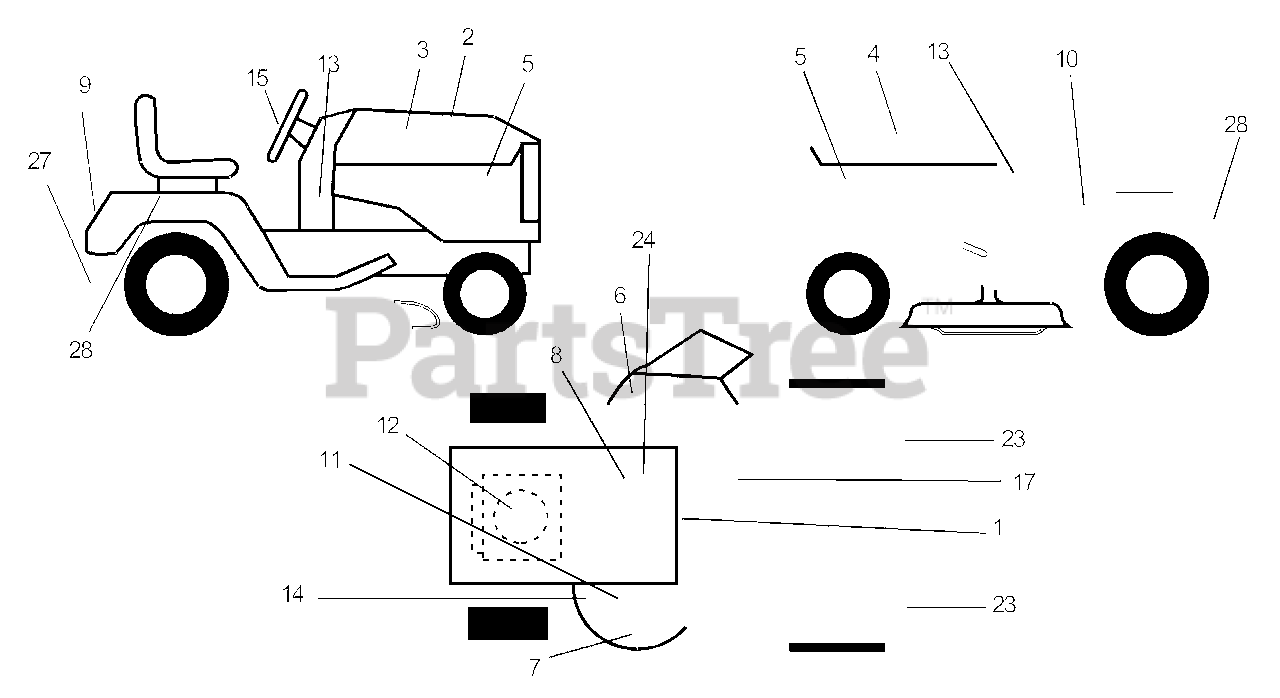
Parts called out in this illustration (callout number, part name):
1	Decal, Operating Instruction
2	Decal, Replt
3	Decal, Hood, RH
4	Decal, Hood, LH
5	Decal, Side Pnl
6	Decal, Warning
7	Decal, Deck Mul
8	Decal, Batt Power Pro
9	Decal, Fender
10	Decal, Danger
11	Decal, Clutch/Brake
12	Decal, Engine
13	Decal, Dash Panel
14	Decal, V-Belt Schematic
15	Decal, Ins. Whl. Strg.
17	Decal, Saddle Brake Parking
23	Reflector, Taillight
24	Decal, Btry Dngr/Psn
27	Decal,Drawbar
28	Decal, Fender Auto
